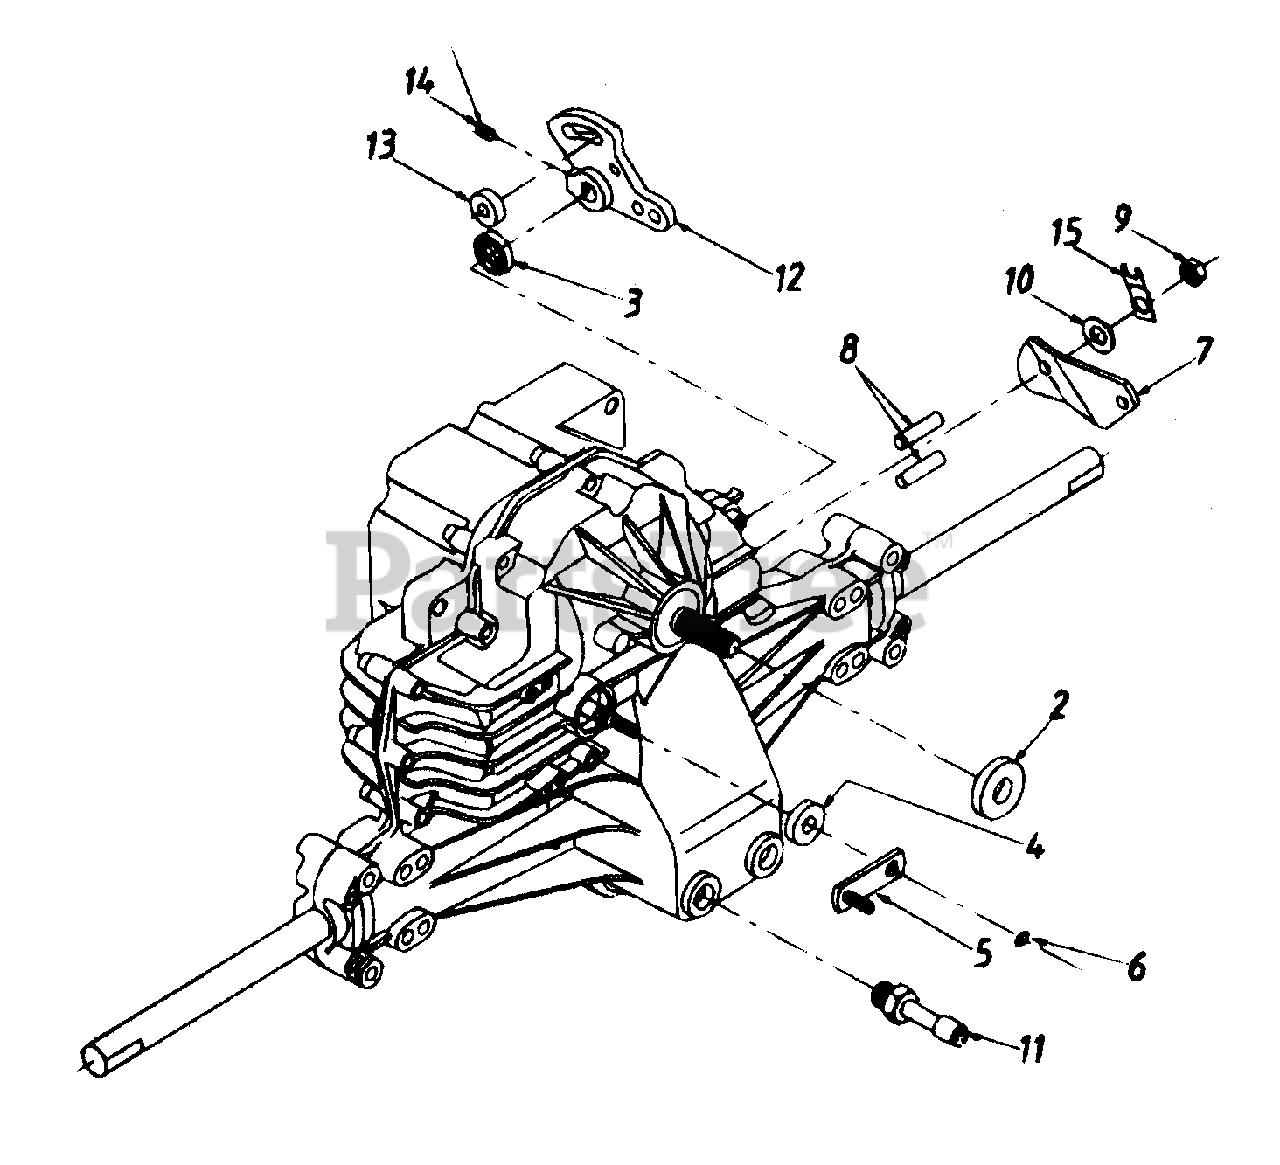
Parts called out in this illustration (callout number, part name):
4	Seal-Lip 10x 25x7
5	Arm-Bypass
6	Ring-Retting
7	Arm-Actuating
8	Pin-Actuating
9	Nut-Hex Lock 5/16-24 UNJC
10	Washer 7/16" x 7/8" x .06"
11	Breather Ass'y.
12	Arm-Control
13	Puck-Dampener
14	Set Screw
15	Strap, Locking
